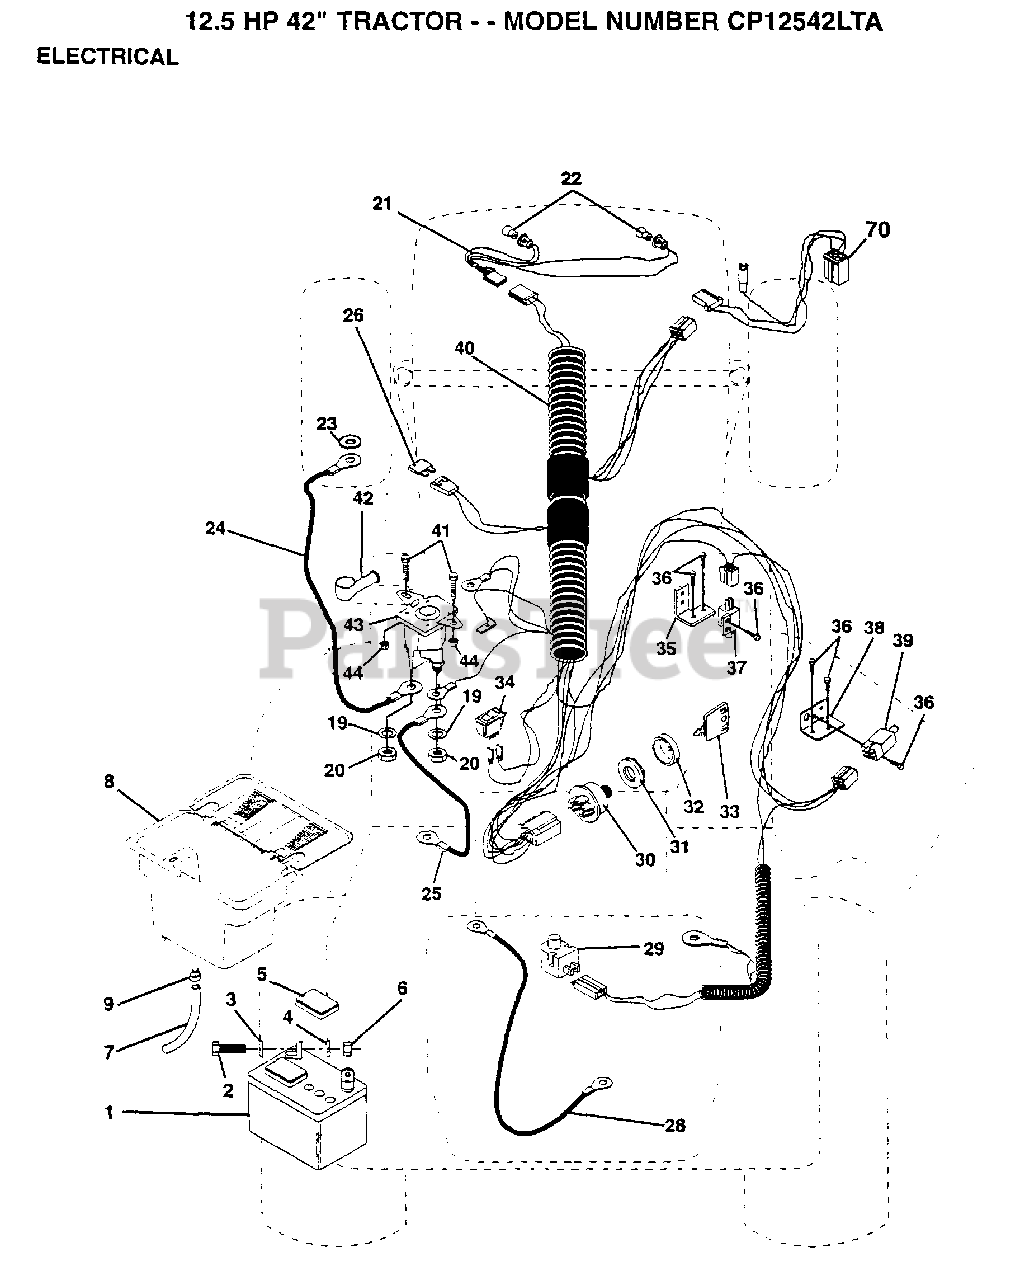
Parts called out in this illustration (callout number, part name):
2	BOLT LT
3	WASHER
4	LOCKWASHER
5	"CAP,BATTERY "
7	TUBE T
9	HOSE CLAMP T
20	NUT
21	"HARNESS,LIGHT SOC"
22	HEADLAMP BULB
23	LOCKWASHER
24	"CABLE T, BATTERY"
26	FUSE HYT
28	CABLE T
29	SWITCH SEAT
32	COVER KEY SWITCH
33	KEY MLD GEN DELTA
34	SWITCH LT
35	BRACKET LT
36	SCREW
37	SWITCH-INTER. GT
38	BRACKET SWITCH IN
39	SWITCH INTERLOCKT
40	HARNESS IGN DASH
41	BOLT HXHD FIN
44	NUT HXKEP 1/4X20
70	HARNESS ENG DUAL
